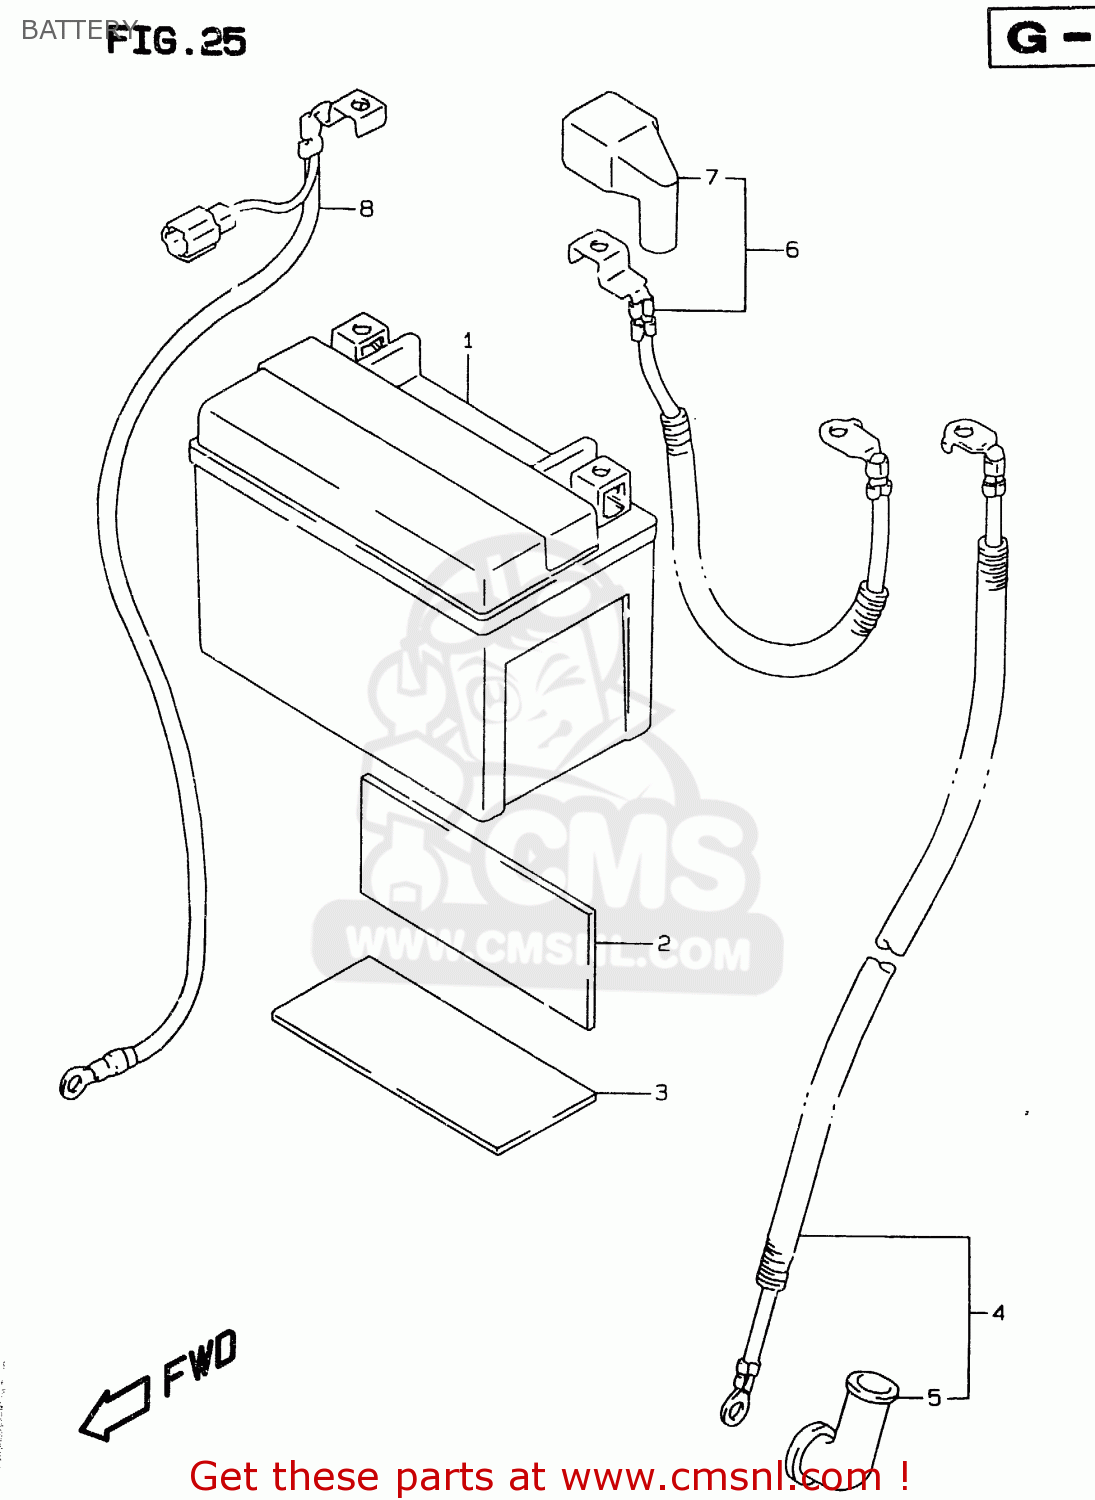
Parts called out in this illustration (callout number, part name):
1	BATTERY ASSEMBLY (12V) FTX
2	PROTECTOR(170X95X3.0)
3	CUSHION,BATTERY(90X45X18)
4	WIRE,STARTER MOTOR LEAD
5	CAP,STARTER MOTOR LEAD
6	WIRE,BATTERY PLUS LEAD
7	CAP,BATTERY PLUS TERMINAL
8	WIRE,BATTERY MINUS
